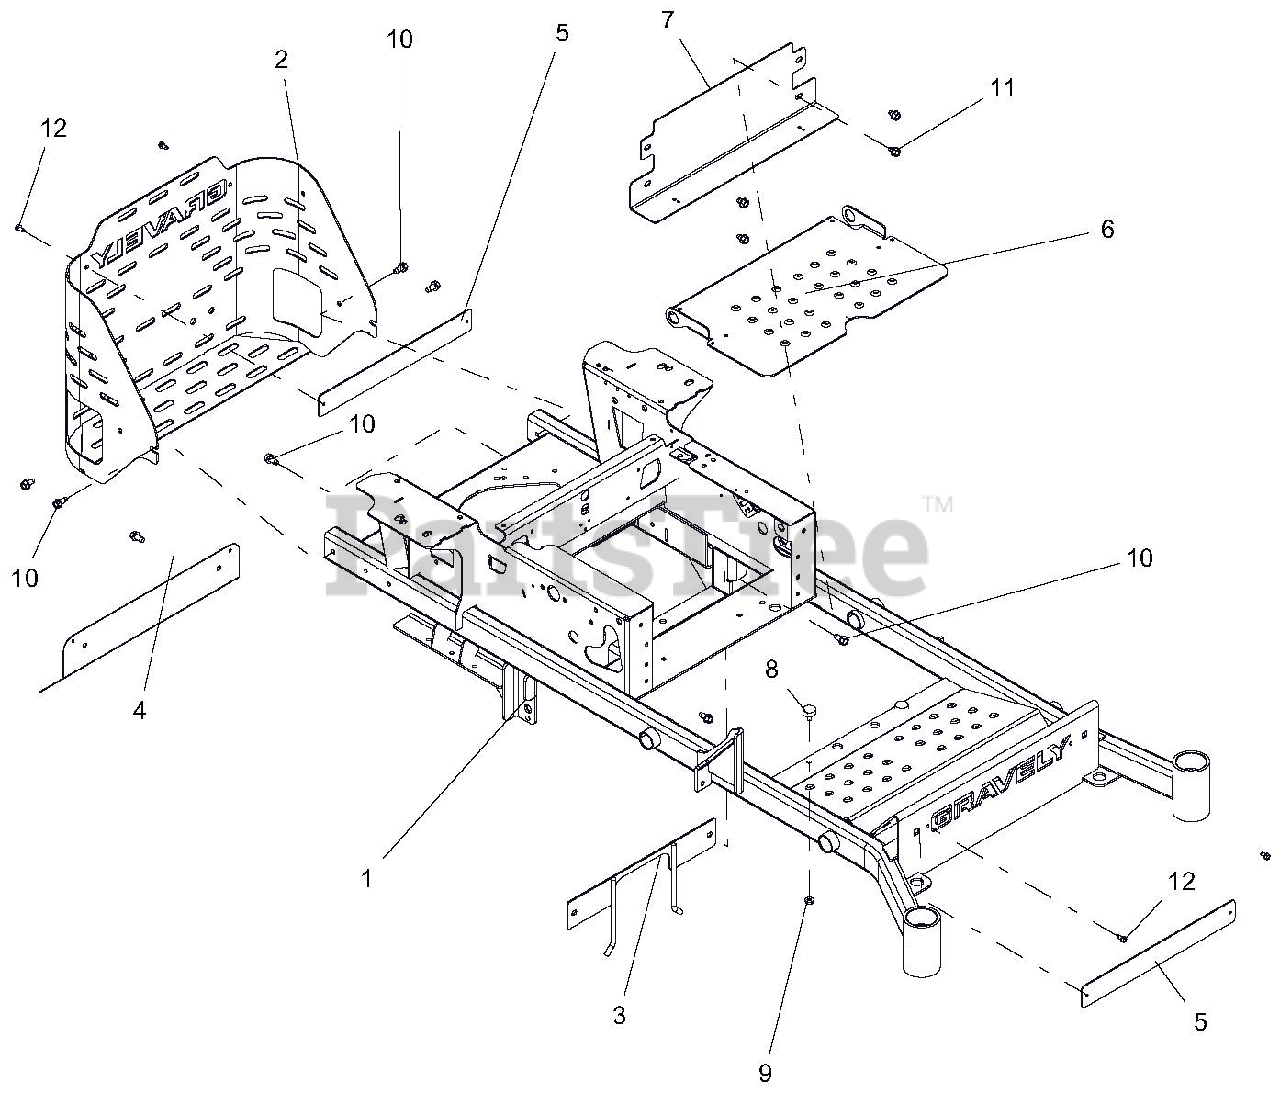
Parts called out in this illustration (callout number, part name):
1	48-52" MAIN FRAME W/SAFETY DECALS
2	REAR BUMPER W/SAFETY DECALS
3	WLDMT, PTO BELT FINGER-BLACK
4	SHIELD, MUFFLER HEAT
5	PLATE, BUMPER 2.00 x 16.50 - BLK
6	FOOT, PLATE W/SAFETY DECALS
7	PLATE, PT/PT100 KICK-RED
8	BUMPER, RUBBER
9	@NUT-SPNLK-FLG .312-18 YWZC
10	SCR-TAP .38-16X.75 HWH TR YWZ
11	SCR-TAP .38-16X.50 HWH TR YWZ
12	SCR-TAP .25-20X.50 HWH TR YWZ
